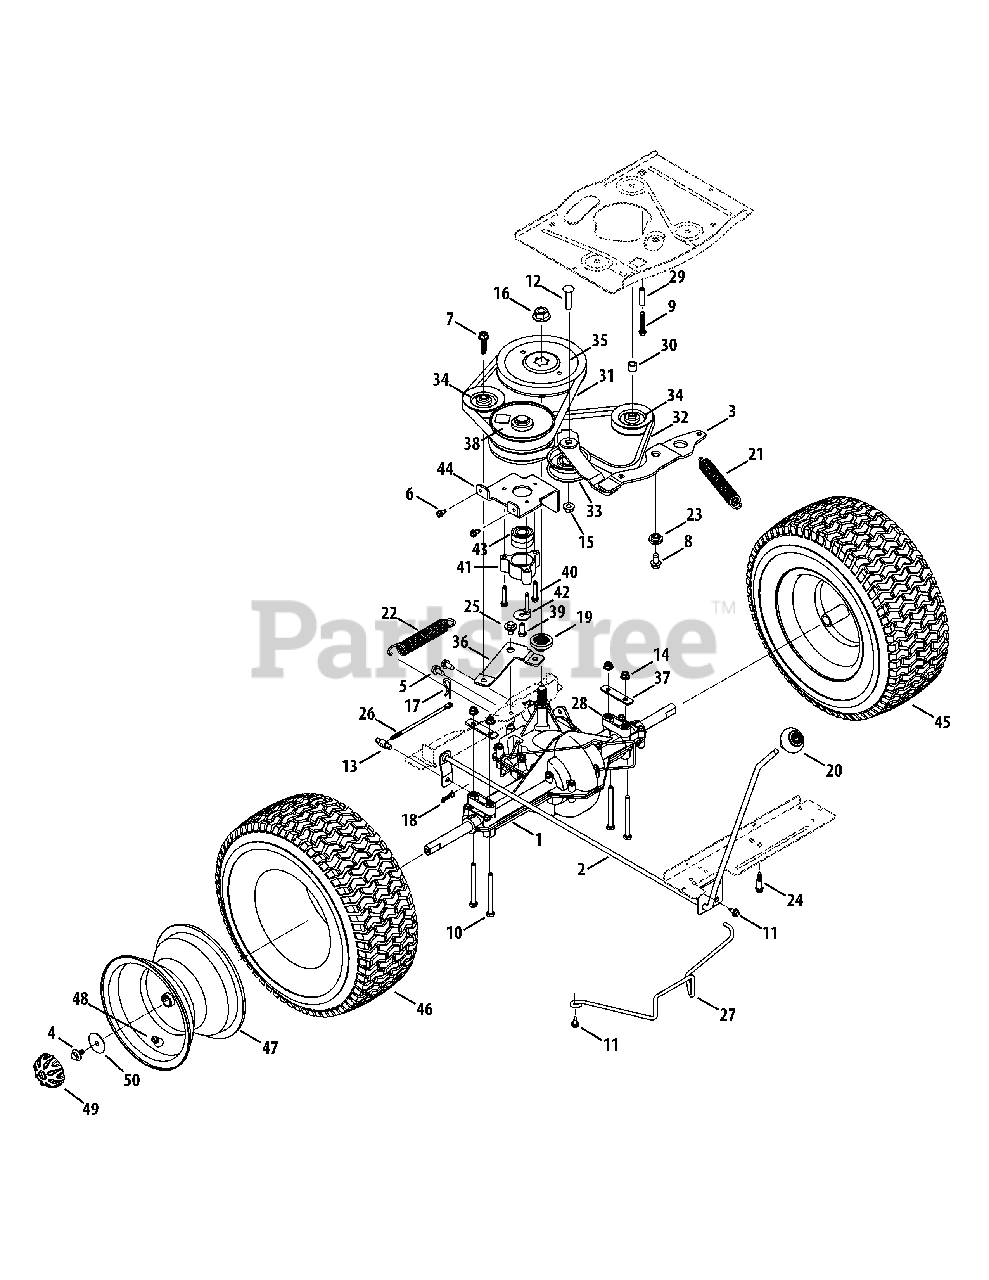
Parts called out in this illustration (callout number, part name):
1	Transmission Assembly
2	Shift Handle Assembly
3	Drive Assembly Idler
4	Screw, 5/16-24 x .750
5	Tap Screw, 5/16-18, .750
6	Tap Scew, 1/4-20, 0.500
7	Screw, 3/8-16 x 1.375
8	Tap Screw, 3/8-16, 0.750
9	Screw, 1/4-20 x 1.750
10	Hex Cap Screw, 5/16-18 x 3.5, Gr5
11	Tap Screw, 1/4-20 x .625
12	Screw, Carriage: 3/8-16 x 1.75"
13	Adjustable Ferrule, 1/4-20 X 1.00
14	Flange Locknut, 5/16-18
15	Flange Lock Nut, 3/8-16
16	Flange Nut, 9/16-18
17	Internal Cotter Pin, .125 Dia.
18	Bow-Tie Cotter Pin
19	Pulley Hub, 5/8 Spline
20	Shift Knob
21	Extension Spring, .94 Dia. X 6.74 Lg.
22	Extension Spring, .97 OD X 6.18
23	Shoulder Spacer, 1.00 X .38 X .38
24	Shoulder Screw, .368 x .75, 1/4-20
25	Shoulder Screw, .560 x .165, 5/16-18
27	Deck Belt Keeper, 30"
29	Spacer, .260 X .372 X 1.420
30	Spacer, .385 x .625 x .500
31	V-Belt, 5L:35.25
32	V-Belt, 5L:35.28
33	Flat Idler Pulley, 2.75 OD
34	V-Type Idler Pulley, 3.06
35	V-Type Pulley, 6.56
36	Rear Idler Arm Bracket
37	Transaxle Mounting Bracket
38	Variable Speed Pulley Assembly
39	Hex Head Lock Screw, 5/16-24:.750
40	Tap Screw, 1/4-20:1.500
41	Bearing Cup
42	Flat Washer, .330x1.250x.060
43	Ball Bearing, 17 X 40 X 12
44	Variable Bracket
46	Tire, 16 x 6.5 x 8 Sq. Shldr.
47	Rim Assembly, 8.0 x 5.38
48	Air Valve
49	Hub Cap
50	Flat Washer, .35 x 1.59 x .062
